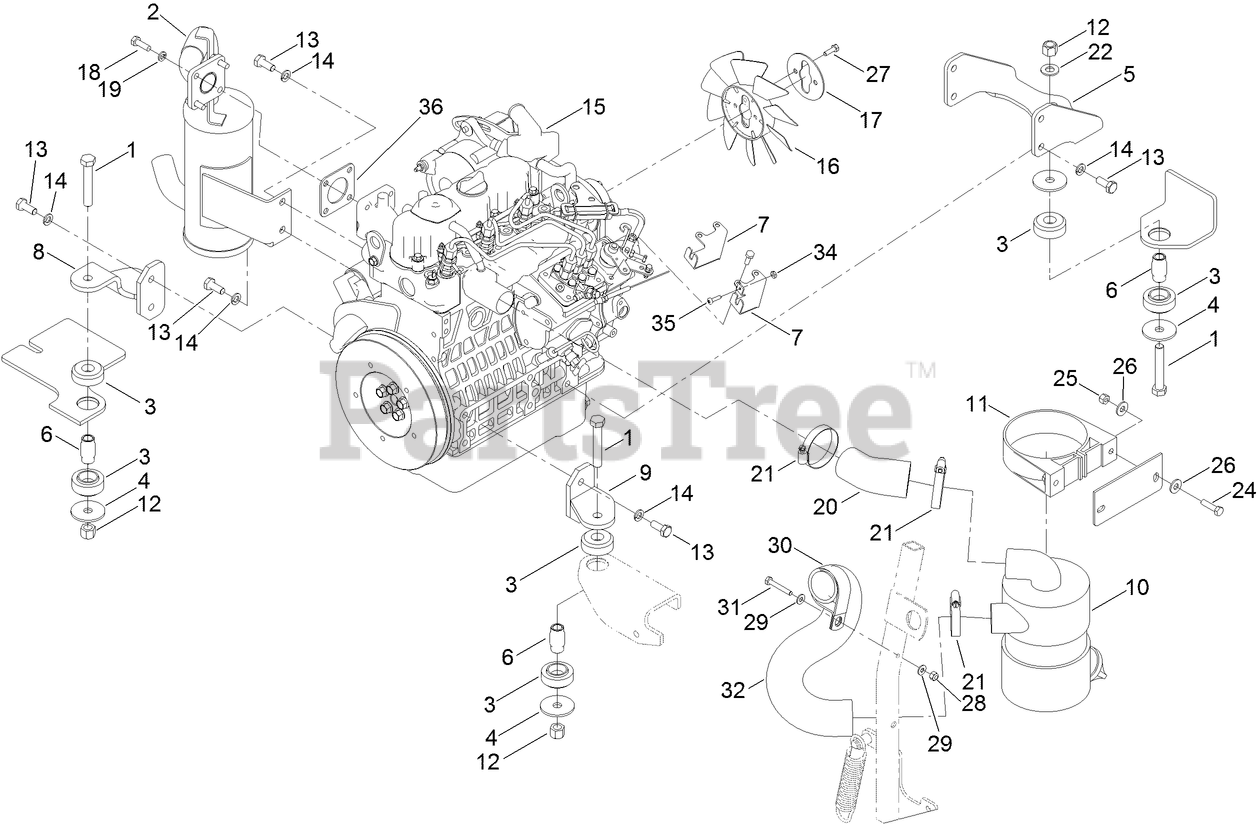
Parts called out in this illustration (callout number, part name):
1	SCREW-HH
2	MUFFLER
3	MOUNT-ISOLATION ASM
4	WASHER-LARGE
5	BRACKET-ENGINE MOUNT, REAR
6	SPACER
7	BRACKET-SUPPORT, THROTTLE
8	SUPPORT-ENGINE, RH
9	SUPPORT-ENGINE, LH
10	AIR CLEANER ASM
11	BRACKET-MOUNTING
12	NUT-LOCK, NI
13	SCREW-HH
14	WASHER-LOCK
15	ENGINE-KUBOTA D902
17	PLATE-REATAINER, FAN
18	SCREW-HH
19	WASHER-LOCK
20	HOSE-INTAKE, AIR CLEANER
21	CLAMP-HOSE
22	WASHER-FLAT
24	SCREW-HH
25	NUT-LOCK, NI
26	WASHER-PLAIN
27	SCREW-HH
28	NUT-LOCK, NI
29	WASHER-FLAT
30	CLIP-LOOM
31	SCREW-HH
32	HOSE-INTAKE, ENGINE
34	NUT-HEX
35	SCREW-TORX
36	GASKET-MUFFLER
